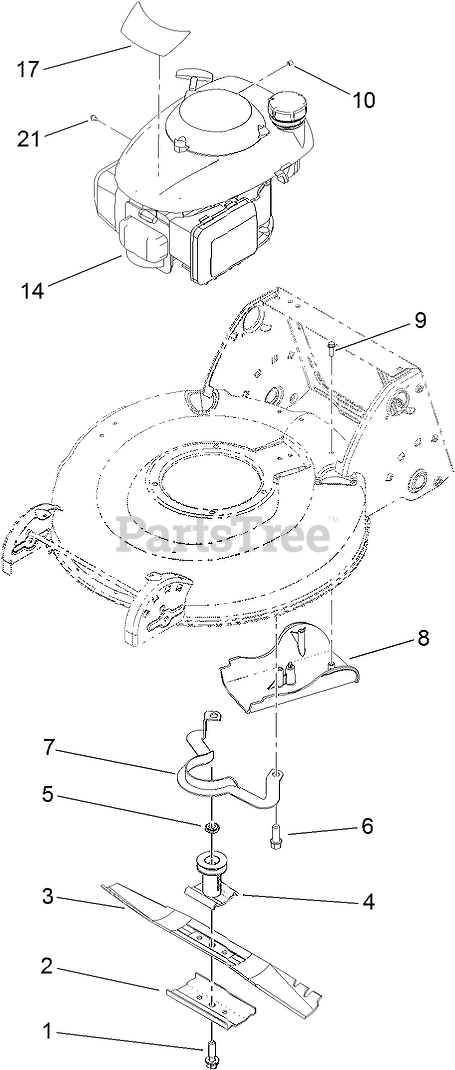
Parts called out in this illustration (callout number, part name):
1	BOLT-BLADE
2	SUPPORT-BLADE
3	BLADE-21 INCH
4	DRIVER-BLADE
5	Spacer-Driver
6	SCREW-TAPTITE
7	Guide-Belt
8	COVER-BELT
9	SCREW-HWH
10	STOP-ROPE
17	DECAL-ENGINE
21	SCREW-HWH
